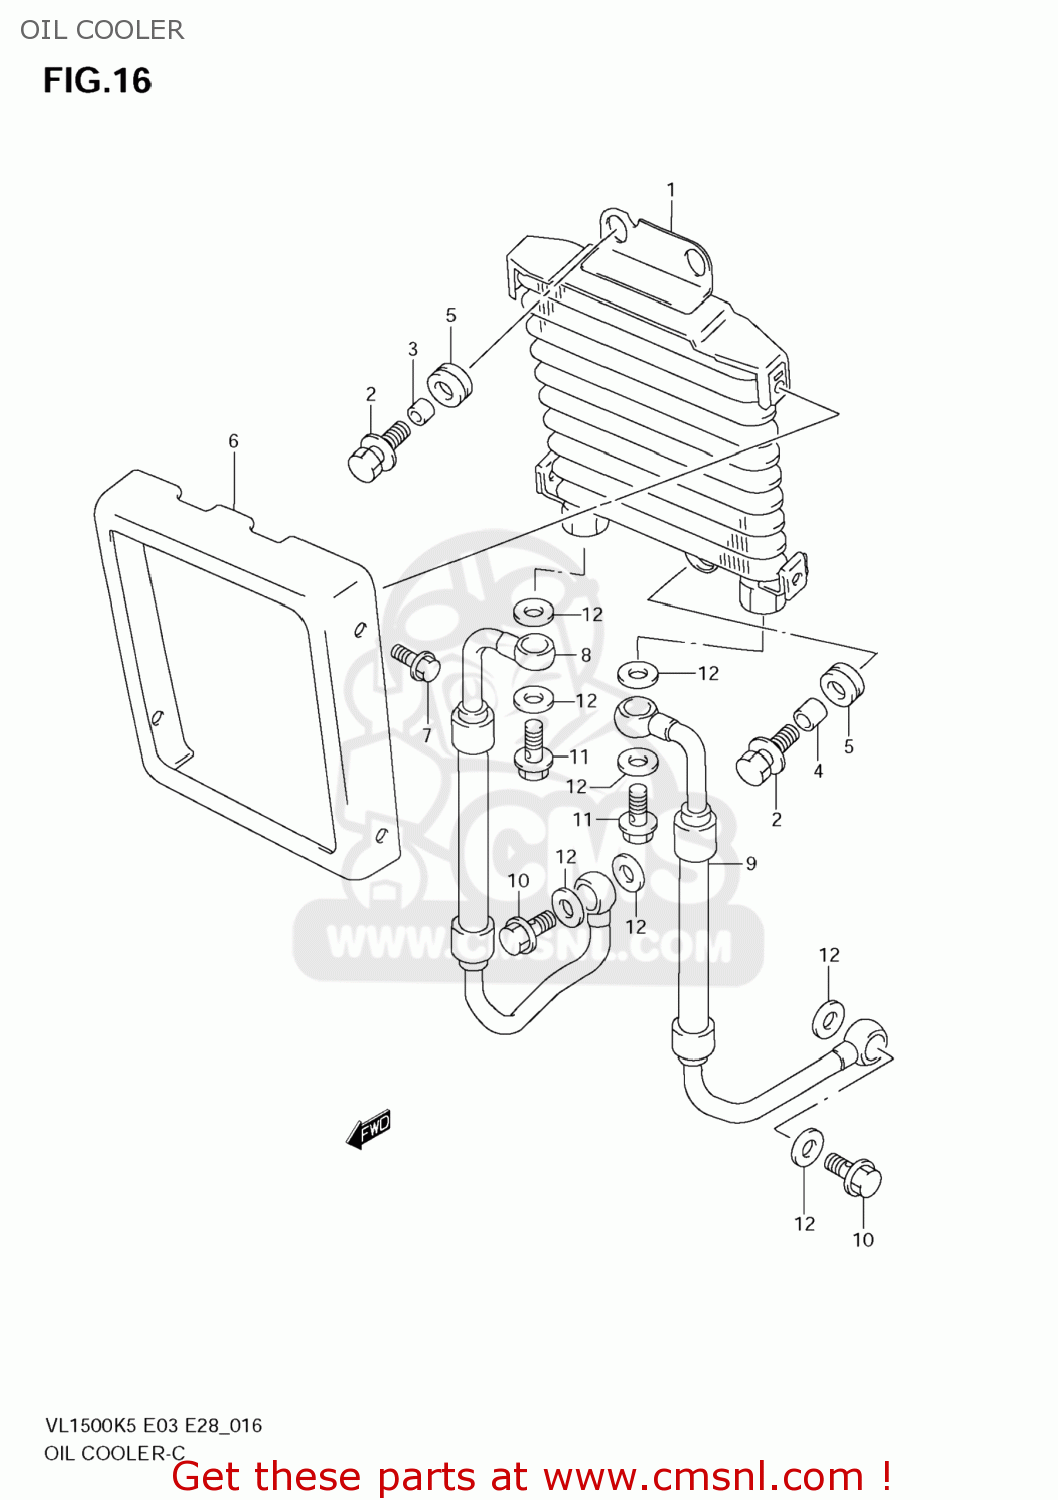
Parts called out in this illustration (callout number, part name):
1	COOLER ASSY,OIL
2	BOLT(6X20)
3	SPACER(6.5X10X10)
4	SPACER(6.5X10.5X12)
5	CUSHION
6	COVER,OIL COOLER
7	SCREW(6X12)
8	HOSE,OIL COOLER,R
9	HOSE,OIL COOLER,L
10	BOLT UNION
11	BOLT UNION
12	GASKET(14X20X1.5) (NAS)
